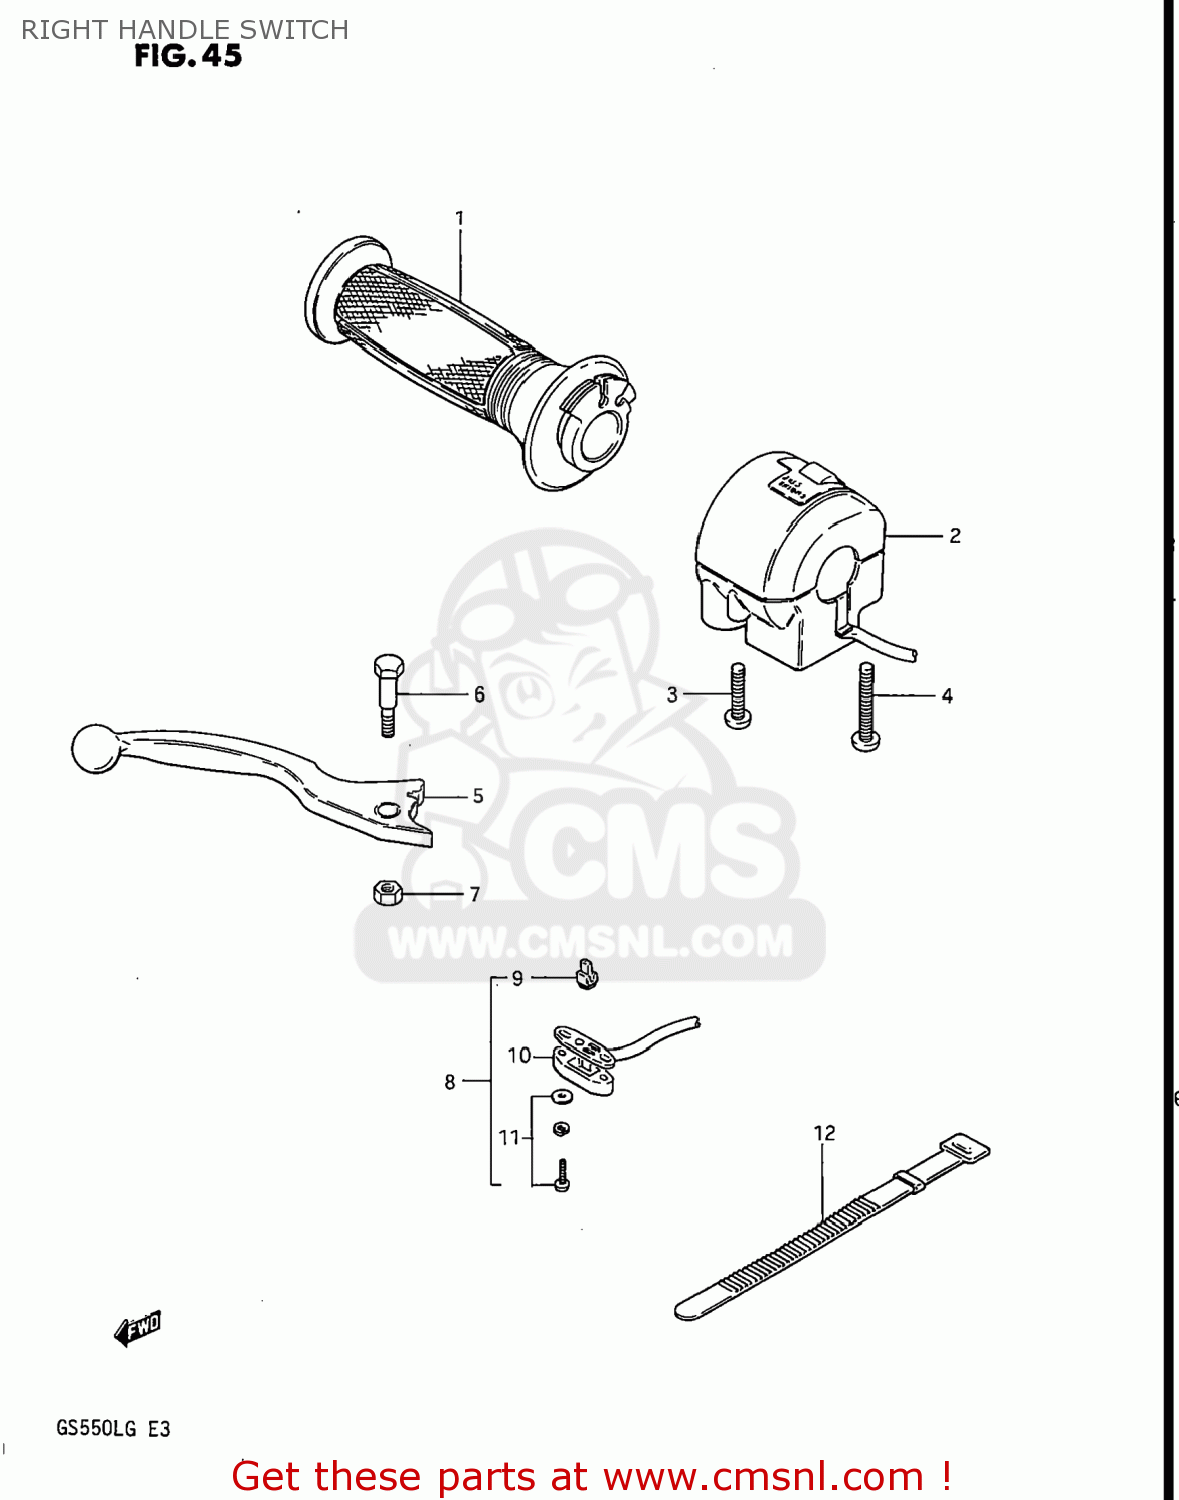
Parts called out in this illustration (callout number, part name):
1	GRIP,THROTTLE
2	SWITCH ASSEMBLY,HANDLE,RIGHT
3	SCREW
4	SCREW
5	LEVER,BRAKE
6	BOLT,LEVER PIVOT
7	NUT
8	SWITCH ASSEMBLY
9	CONTACT,SWITCH
10	COVER,FR BK TERMINAL BASE
11	SCREW
12	CLAMP(L:120)
